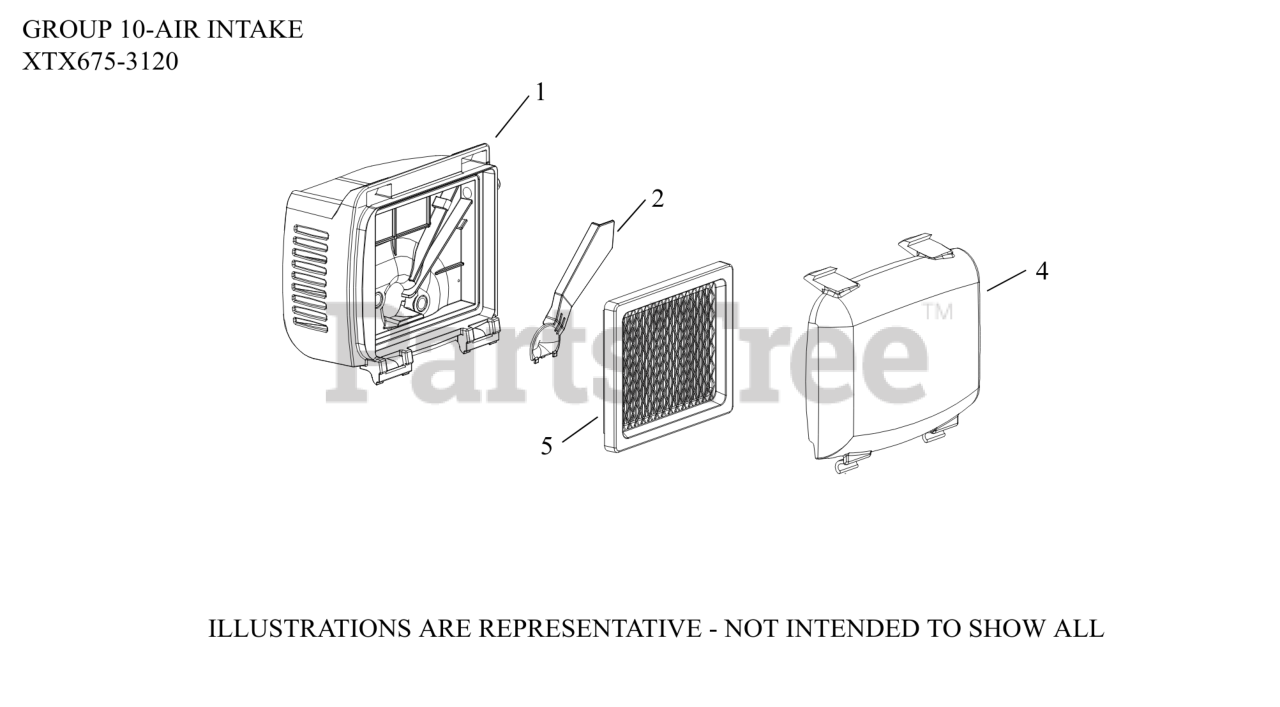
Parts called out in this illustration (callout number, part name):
1	BASE, AIR CLEANER
4	COVER, AIR CLEANER
5	ELEMENT, AIR FILTER
